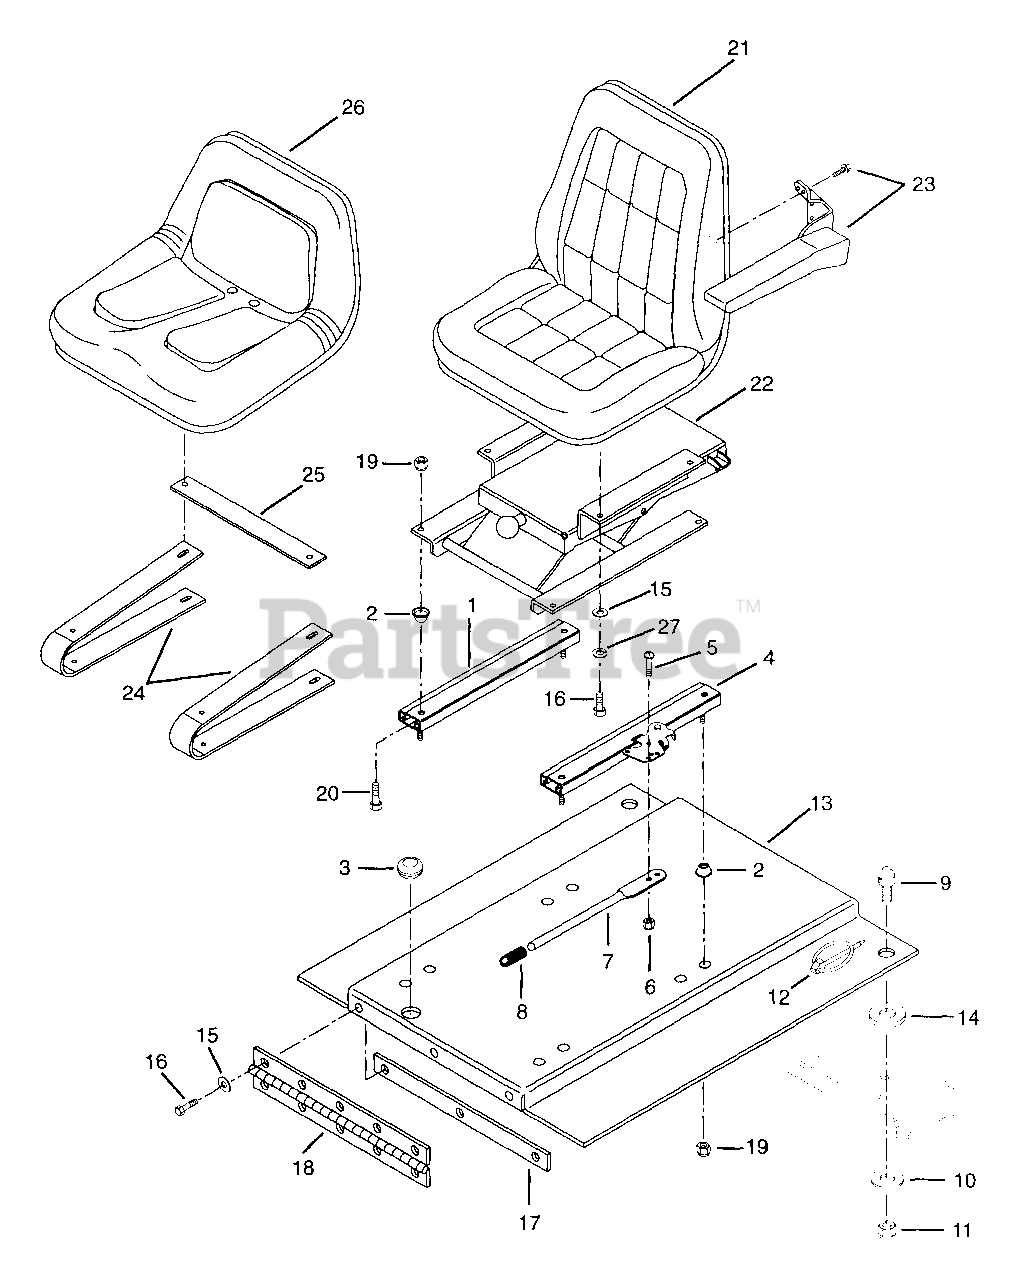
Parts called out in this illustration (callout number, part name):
1	Adjuster, Seat
2	Seat Slide Spacer
3	Grommet 75 x 1.06 x 1.38
4	Adjuster, Seat w/Latch
5	Screw-Machine 10-24 x .625
6	Nut-Locking 10-24
7	Seat Slide Handle
8	Tip-Brake Lock Lever
9	Pin, Catch
10	Washer-Flat-Steel .531 x 1.062 x .095
11	Nut-Locking-Nylon .50-13 Grade 5
12	Pin-Klik .25 x 1.75
13	Plate, Deck
14	Washer-Snub-Steel .53 x 2.38 x .125 (989300,301)
15	Washer-Flat-Steel .344 x .688 x .065
16	Bolt-Hex .31-18 x .75 Grade 5
17	Plate, Clamping
18	Hinge
19	Nut-Locking-Nylon .312-18 Grade 2
20	Bolt-Hex .31-18 x 1.38
21	Seat, Pro Master
22	Seat, Suspension
23	Kit-Pro Master Arm Rest
24	Spring, Seat
25	Plate, Control Shaft
26	Seat, V-560 High Back
27	Bolt-Hex .31-18 x 1.00 Grade 5
